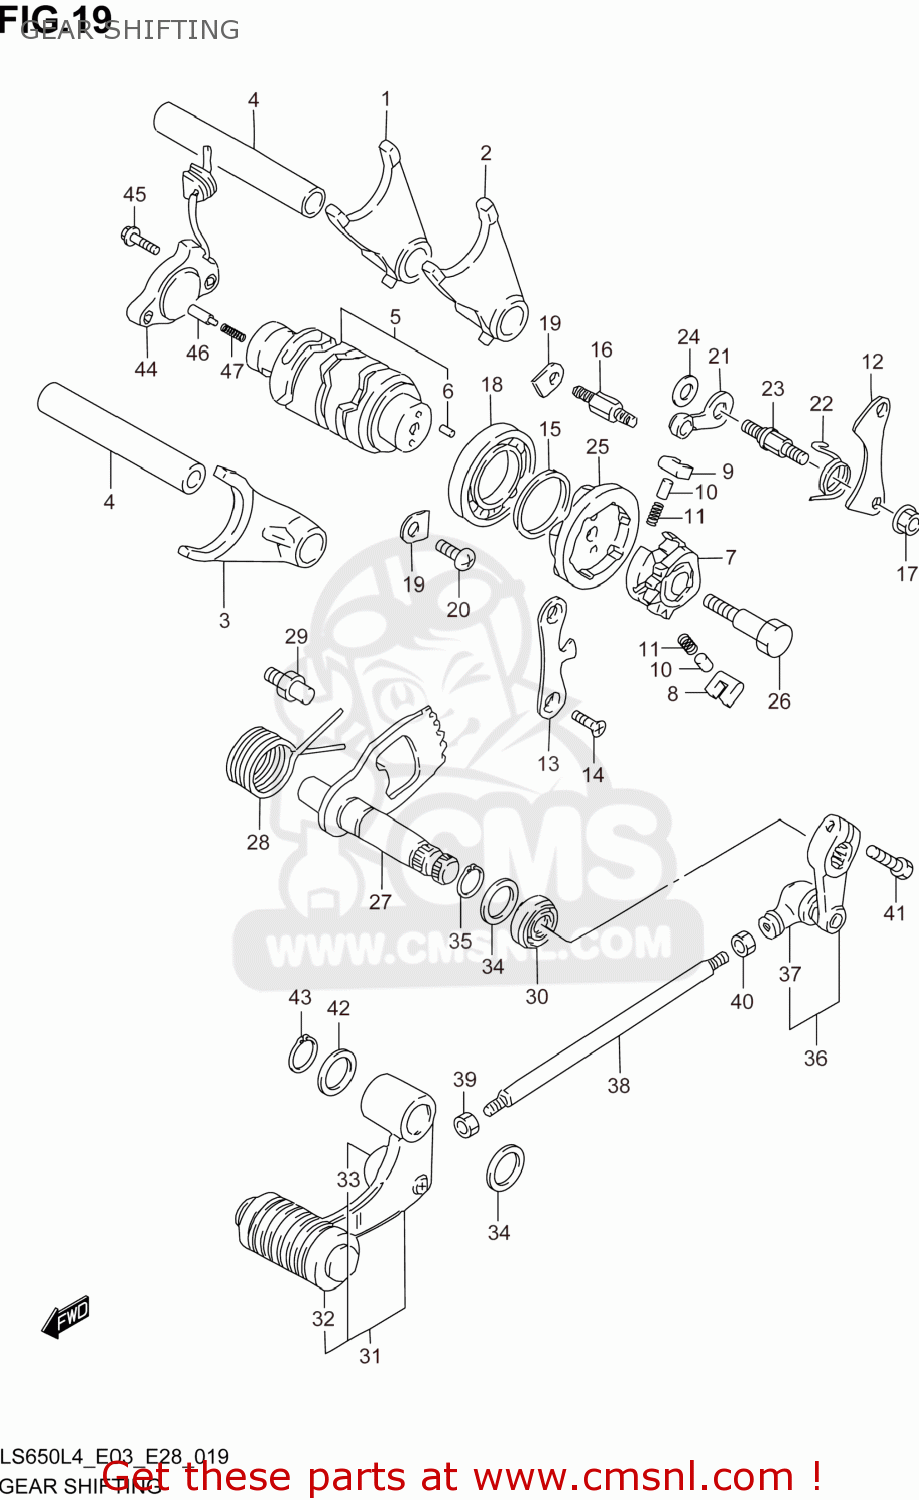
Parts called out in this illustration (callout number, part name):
1	FORK,GEAR SHIFT NO.1
2	FORK,GEAR SHIFT NO.2
3	FORK,GEAR SHIFT NO.3
4	SHAFT,GEAR SHIFT FORK
5	CAM,GEAR SHIFT
6	PIN
7	GEAR,GEAR SHIFT CAM DRIVEN
8	PAWL,GEAR SHIFT NO.1
9	PAWL,GEAR SHIFT NO.2
10	PIN(5X8)
11	SPRING
12	LIFTER,GEAR SHIFT POLE
13	GUIDE,GEAR SHIFT CAM
14	SCREW
15	WASHER(25X32X3)
16	BOSS,SHIFT PAWL LIFTER
17	NUT
18	BEARING(25X47X8)
19	RETAINER
20	SCREW
21	STOPPER,GEAR SHIFT CAM
22	SPRING
23	SUPPORT,CAM STOPPER ARM
24	WASHER
25	PLATE,GEAR SHIFT CAM
26	PIN,SHIFT CAM DRIVEN GEAR
27	SHAFT,GEAR SHIFT
28	SPRING
29	STOPPER,GEAR SHIFT ARM
30	SEAL,OIL (12X22X9)
31	LEVER ASSY,GEAR SHIFT
32	RUBBER,GEAR SHIFT PEDAL
33	COVER,DUST
34	WASHER(12.5X20X1)
35	CIRCLIP
36	ARM,GEAR SHIFT LINK
37	COVER,DUST
38	ROD,GEAR SHIFT LINK
39	NUT
40	NUT
41	BOLT
42	WASHER
43	CIRCLIP
44	BASE ASSY,NEUTRAL SW TERMINAL
45	SCREW
46	PIN(5X15.5)
47	SPRING
